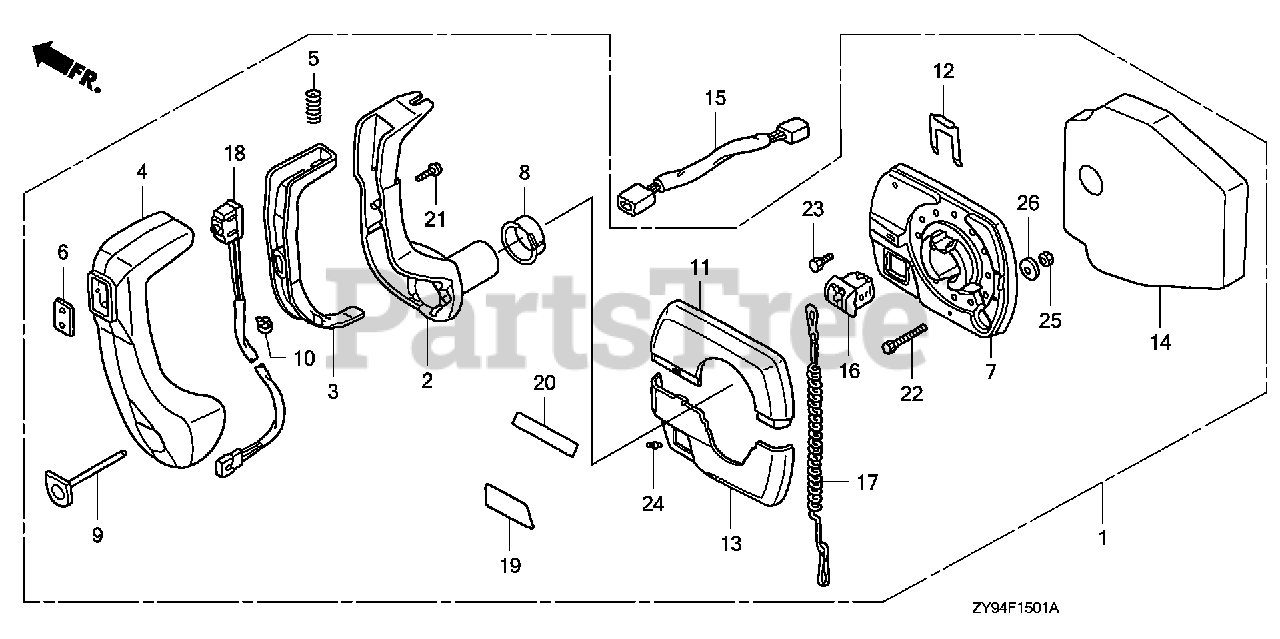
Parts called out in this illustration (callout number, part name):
1	BOX ASSY., REMOTE CONTROL (PANEL MOUNT) (NA USE ALT:06240-ZW7-U00)
2	HANDLE, REMOTE CONTROL
3	LEVER, HANDLE LOCK
4	GRIP, REMOTE CONTROL HANDLE
5	SPRING, REMOTE CONTROL HANDLE
6	COVER, GRIP
7	HOUSING ASSY., REMOTE CONTROL BOX (A)
8	BUSHING
9	BUTTON, THROTTLE
10	BAND B, CABLE
11	HOUSING, REMOTE CONTROL BOX (B)
12	RETAINER
13	HOUSING, REMOTE CONTROL BOX (C)
14	HOUSING ASSY. (INNER) (PANEL MOUNT)
15	HARNESS ASSY., POWER TRIM-TILT
16	SWITCH ASSY., EMERGENCY STOP
17	WIRE, EMERGENCY
18	SWITCH ASSY., POWER TRIM-TILT (A)
19	MARK, REMOTE CONTROL (A)(PANEL)
20	MARK, REMOTE CONTROL (B)(FOR STARBOARD)
20	MARK, REMOTE CONTROL (C)(FOR PORT)
21	SCREW A (NOT AVAILABLE)
22	SCREW B
23	SCREW C
24	SCREW SET (1/4-20X16")
25	NUT (1/4X20)
26	WASHER
